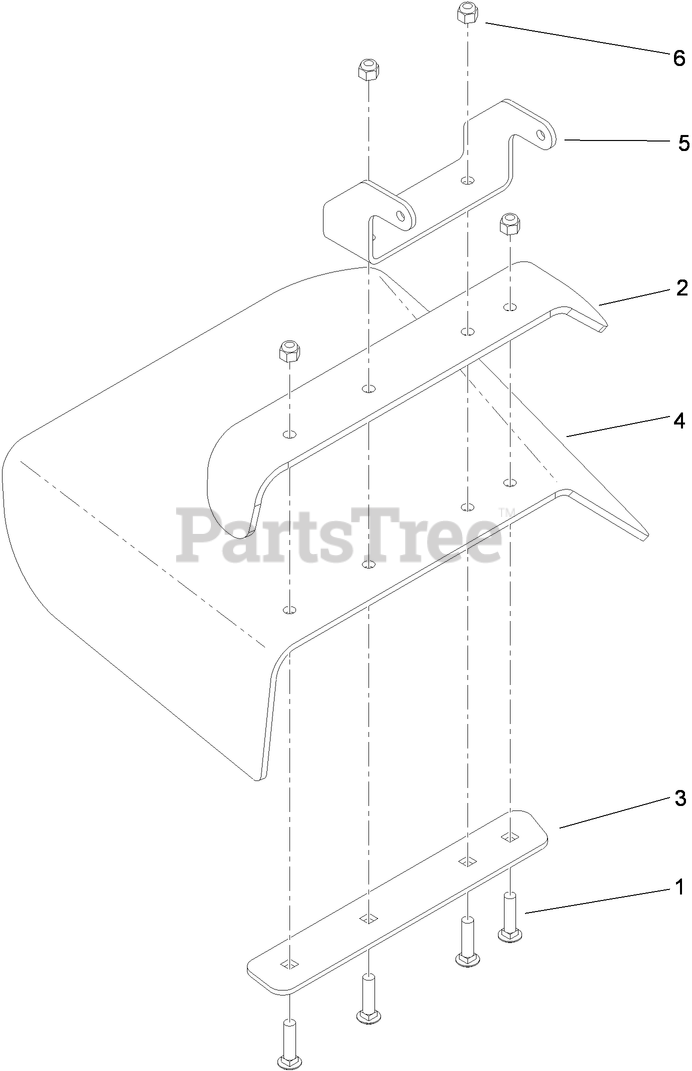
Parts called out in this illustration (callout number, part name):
1	SCREW-CARR
2	DEFLECTOR
3	STRAP-DISCHARGE
4	DEFLECTOR-RUBBER
5	BRACKET-MOUNTING, DEFLECTOR
6	NUT-LOCK, NI
